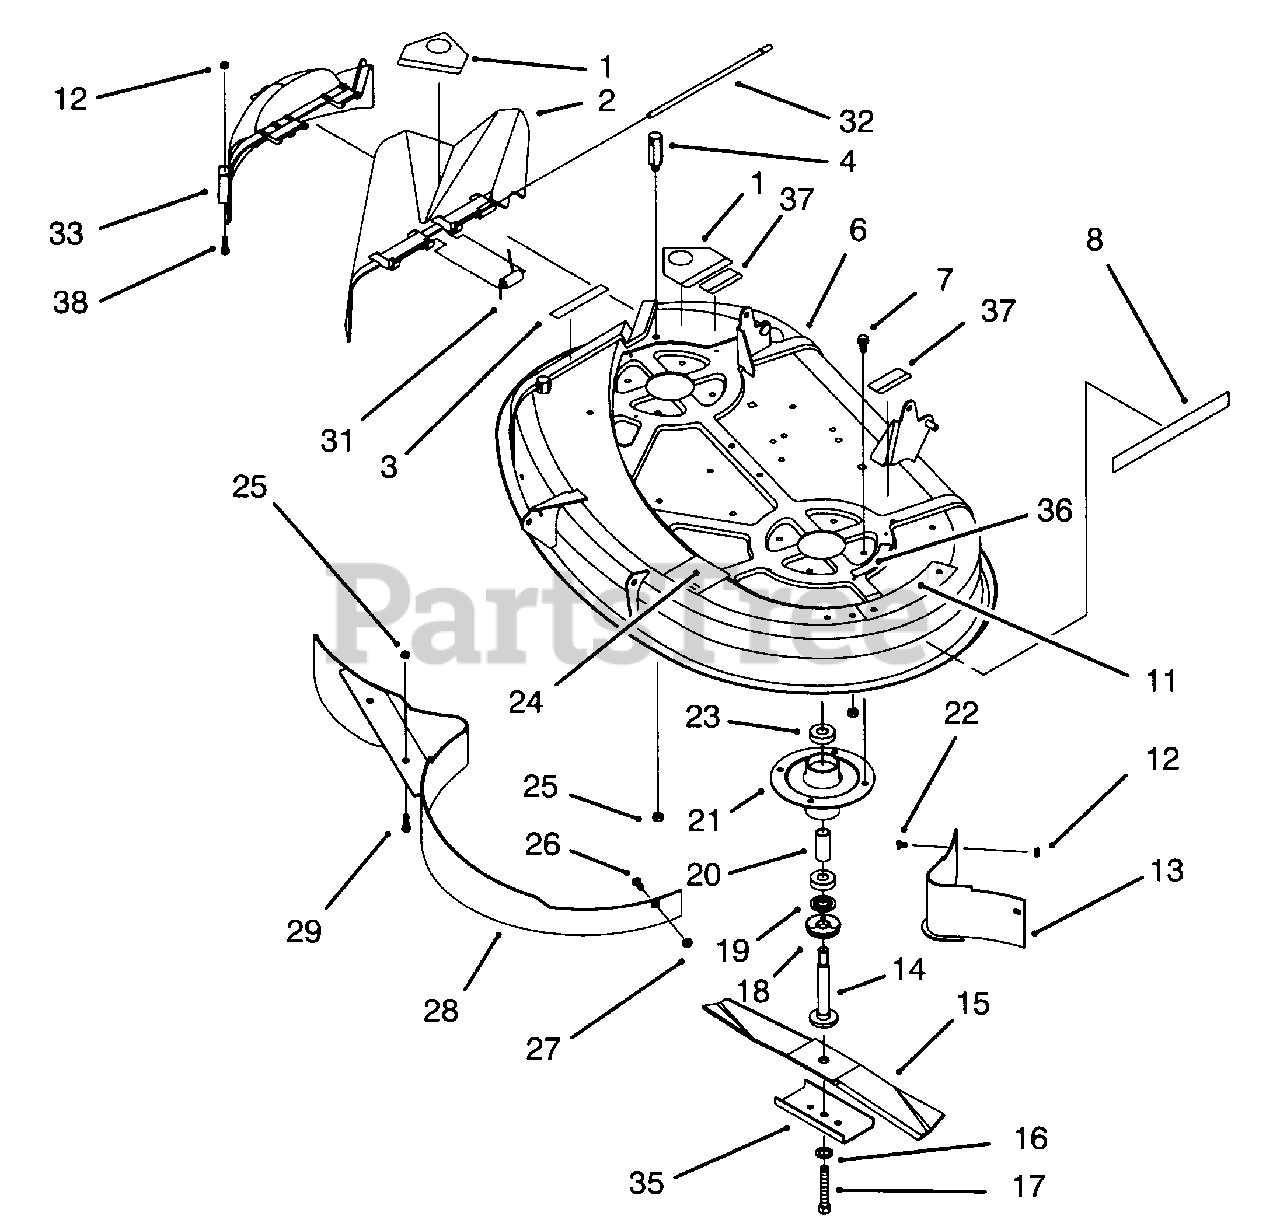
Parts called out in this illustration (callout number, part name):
1	Decal-Danger
2	Deflector-Deck
3	Decal-Deflector Danger
4	Post-Rear Pivot
6	Deck-38"
7	Screw-Taptite
8	Decal-38" Easy Mulch
11	Decal-Danger
12	Nut-Lock
13	Baffle-Rear
14	Shaft-Spindle
15	Blade-Power Mulch
16	Washer-Belleville
17	Bolt-Blade
18	Shield-Bearing
19	Spacer-Hardened
20	Spacer-Bearing
21	Housing-Spindle
22	Screw-Hex Hd. Cap
23	Bearing-Spindle
24	Decal-Belt Guide
25	Nut-Lock
26	Bolt-Carriage
27	Nut-Lock
28	Baffle-Power-Mulch
29	Screw-Hex Hd. Cap
31	Spring-Torsion
32	Rod-Deflector Hinge
33	Cover-Discharge
35	Stiffener-Blade
36	Decal-Shield Danger
37	Decal-Spring Caution
38	Screw-Hex Hd. Cap
